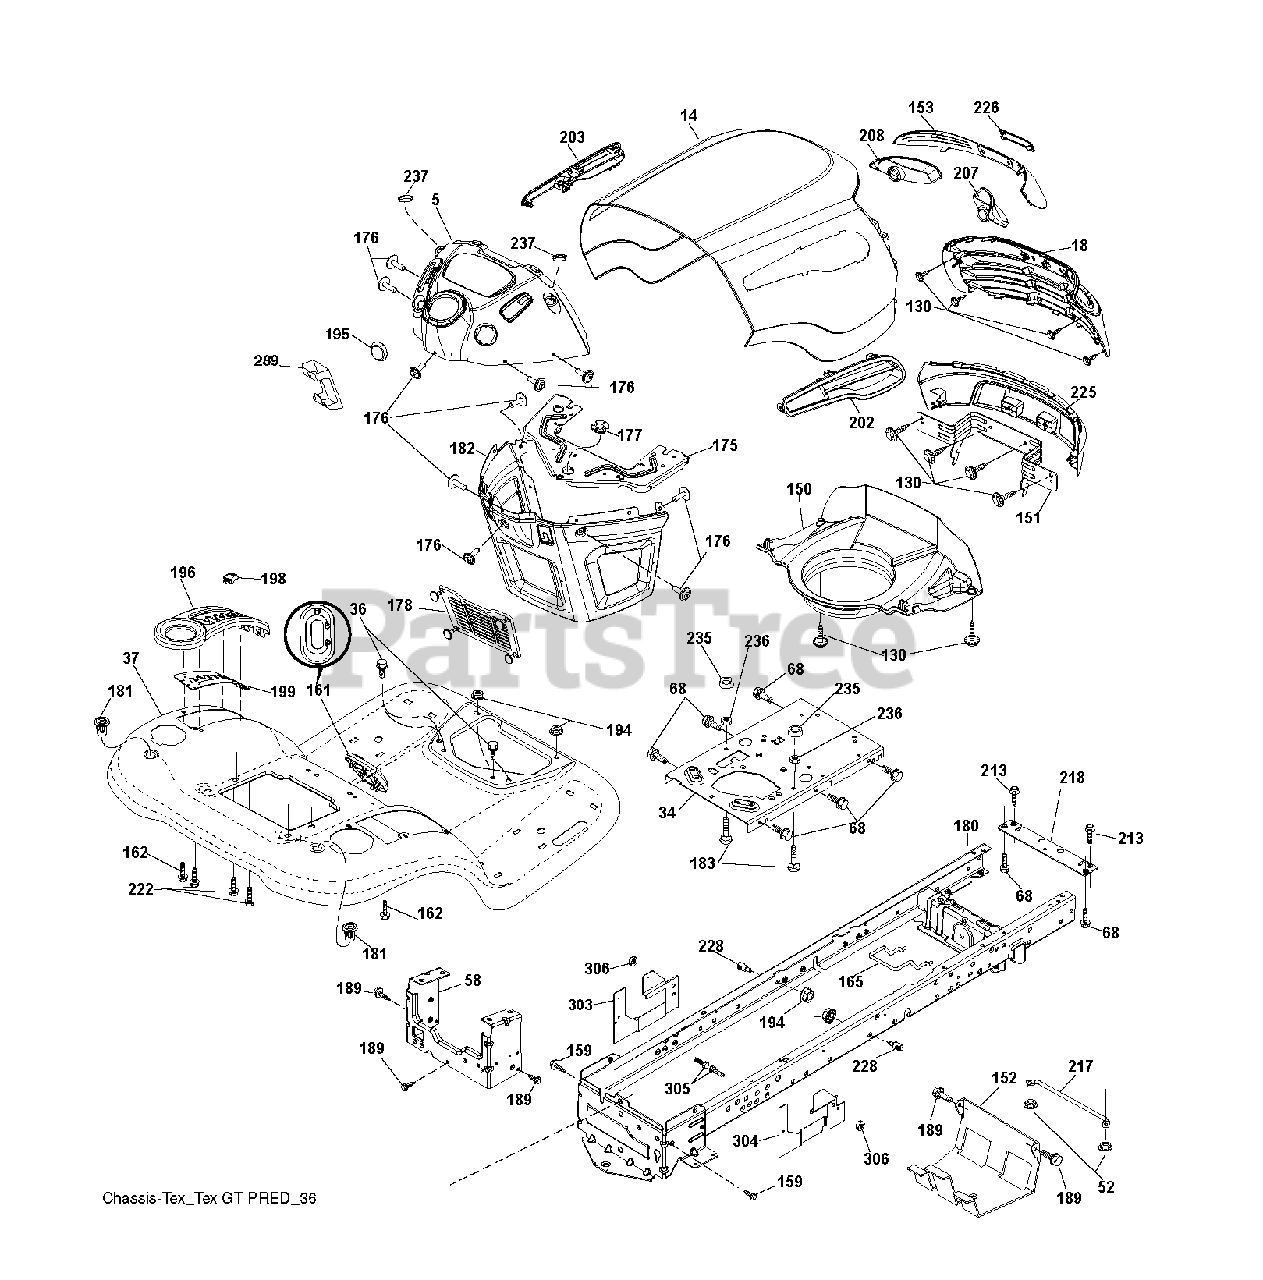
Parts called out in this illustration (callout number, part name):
34	PLATE.ENGINE.WELDED.CHASSIS
36	SCREW 5/16"
52	LOCKNUT
58	DRAWBAR.UPPER.2PC,LRG.FENDER
130	SCREW.#10 X 0.750.BOS THREAD
152	SHIELD BROWNING
159	SCREW, 3/8-16X3/4
161	CONSOLE.FUEL.WINDOW.STGT.BLACK
162	SCREW.HI-LO.CONSOLE
165	SUPPORT.TANK.REAR.W/TE
175	PLATE.CROSSMEMBER.HUSQ
176	SCREW.#10-24X5/8.RN.QU
177	BUSHING,STEERING
178	CARGO.ASM.NET.TXGT.W/C
180	CHASS.WLDMNT.TLT.12GA/2PC.20"
181	FEND/FTRST.PCH.CPH.NFW
182	DASH.LOWER.COMMON.12V.ADAPTOR
183	BOLT.5/16-18X1-1/4 FULL THD
189	SCREW
194	NUT LOCK HEX FLANGE 5/16-18
195	PLUG.HOLE.DASH.LOWER.12V.BLK
198	INDICATOR DECK LIFT
199	PLATE DECK LIFT
213	BOLT
217	ROD.PIVOT.HOOD
218	X-PIECE.HOOD.STOP.NON/
222	SCREW.1/4-20X5/8
228	STUD.FASTNER.W/ANTI-ROTATE
235	SPACER FENDER
236	NUT.CENTERLOCK.5/16-
237	PLUG.MOUNT.CARGO.BLK
289	PLUG.N/CRUISE.COMMON.YT/GT.BLK
306	NUT LOCK FLG 3/8-16 UNC
